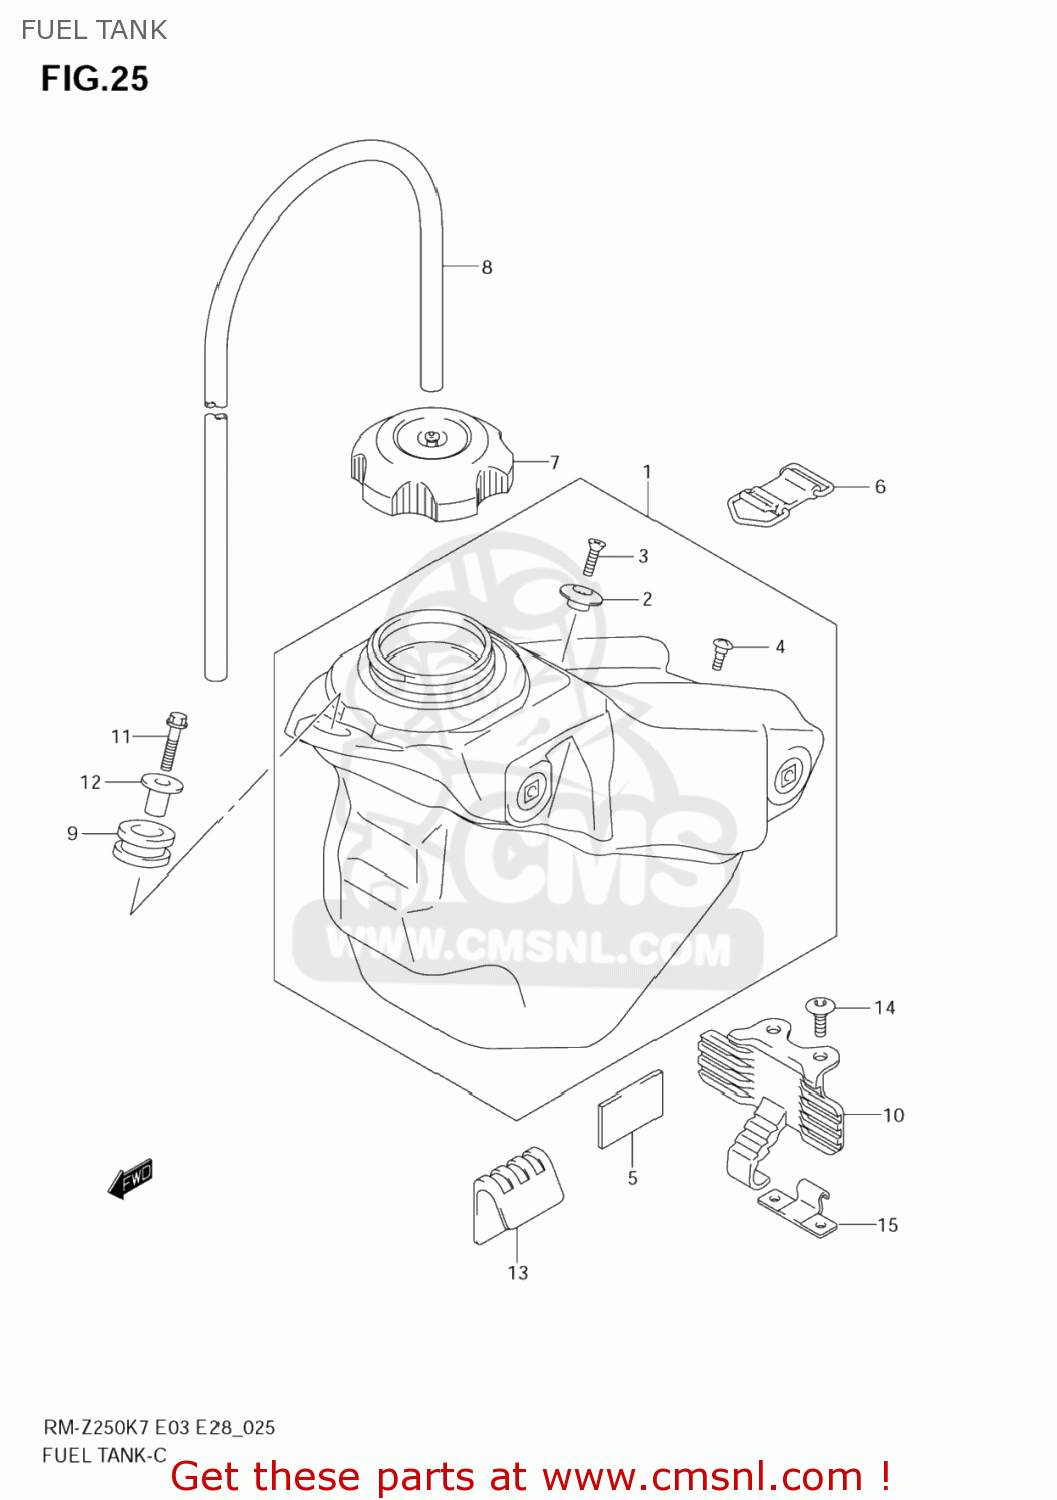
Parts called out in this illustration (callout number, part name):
1	TANK,FUEL(BLACK)
2	HOOK,SEAT FR
3	SCREW
4	SCREW(6X13.5)
5	CUSHION,FUEL TANK
6	BAND,FUEL TANK RR
7	CAP ASSY,FUEL TANK FILLER
8	HOSE(5X8.2X600)
9	CUSHION,FUEL TANK FR
10	CUSHION,FUEL TANK RR
11	BOLT(6X30)
12	SPACER
13	CUSHION,TANK SIDE
14	SCREW(6X16)
15	HOOK,FUEL TANK BAND
